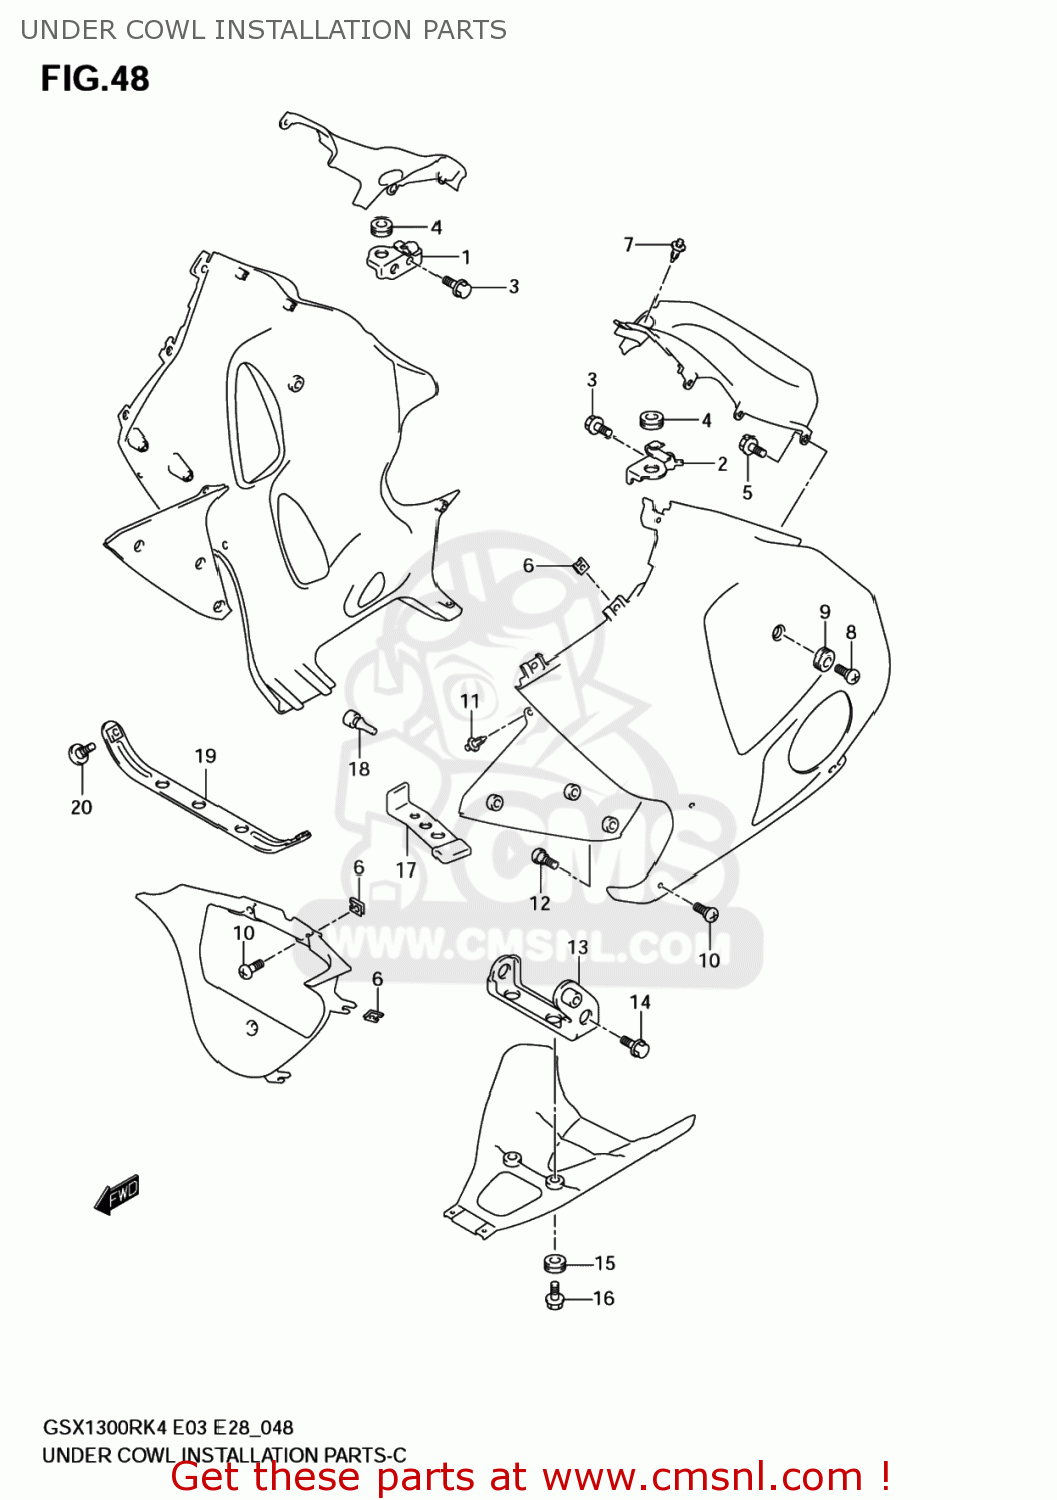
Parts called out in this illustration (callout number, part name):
1	BRACKET,PANEL,R
2	BRACKET,PANEL,L
3	BOLT
4	CUSHION
5	SCREW
6	NUT,COWL
7	CLIP
8	SCREW(6X20)
9	CUSHION
10	SCREW(5X16)
11	CLIP(BLACK)
12	SCREW
13	BRACKET,RR UNDER COWLING
14	BOLT
15	CUSHION
16	SCREW(6X20)
17	BRACKET,UNDER COWLING,L
18	CUSHION
19	PLATE,UNDER COWLING
20	SCREW(5X16)
